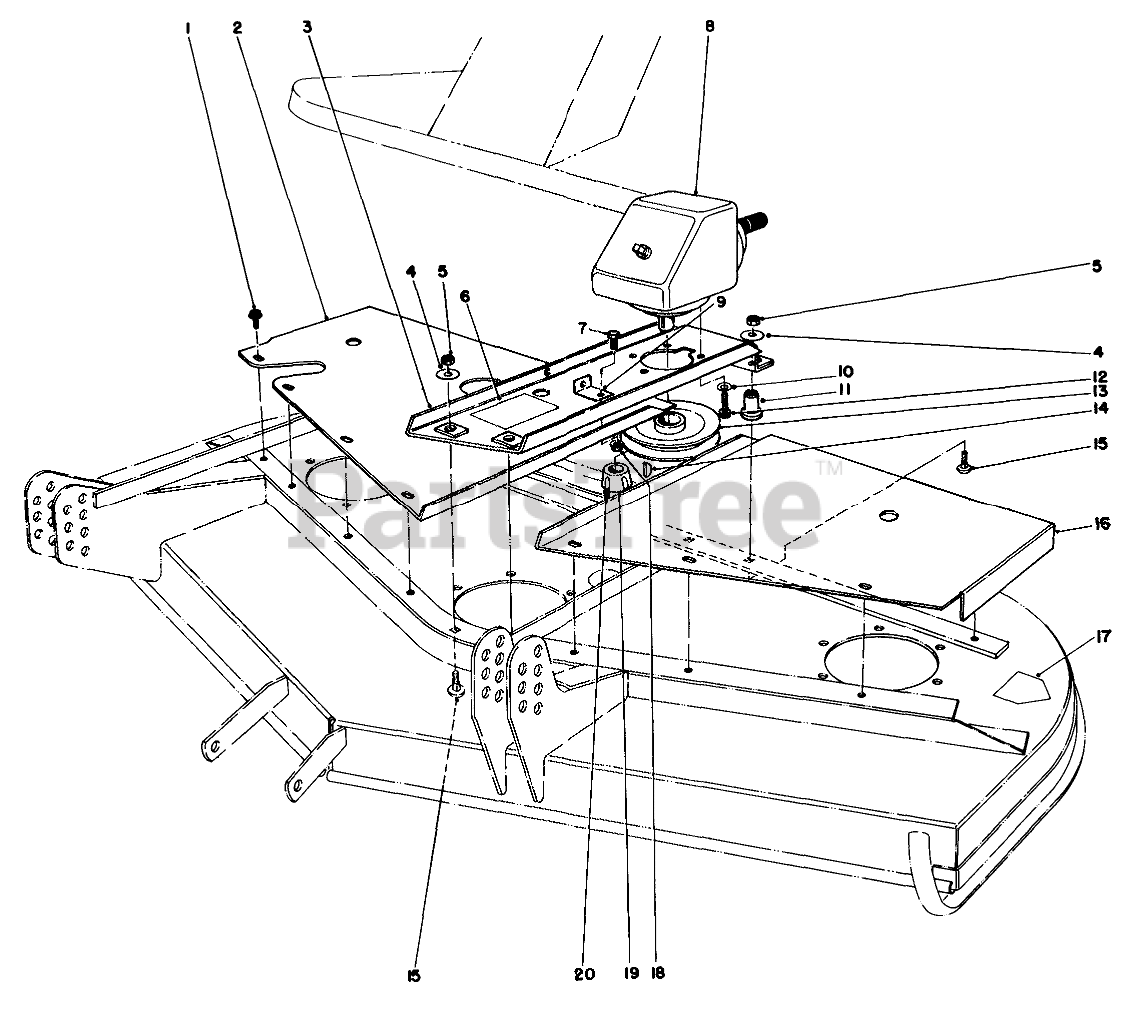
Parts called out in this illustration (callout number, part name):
1	SCREW-HHFTF
2	RH COVER WA R
3	GEARBOX BASE WA R
4	WASHER
5	NUT-LOCK, SIDE
6	DECAL
7	SCREW-HH
8	GEAR BOX ASM
9	EXTENSION BRKT R
10	WASHER-LOCK
11	MOUNT
12	SCREW-HSH
13	PULLEY
14	KEY-WOODRUFF
15	SCREW-CARR
16	LH COVER WA R
17	DECAL-DANGER
18	NUT-HF
19	Bushing-Taper Lock (Incl. Ref. #20)
20	SCREW-SET, HSH
